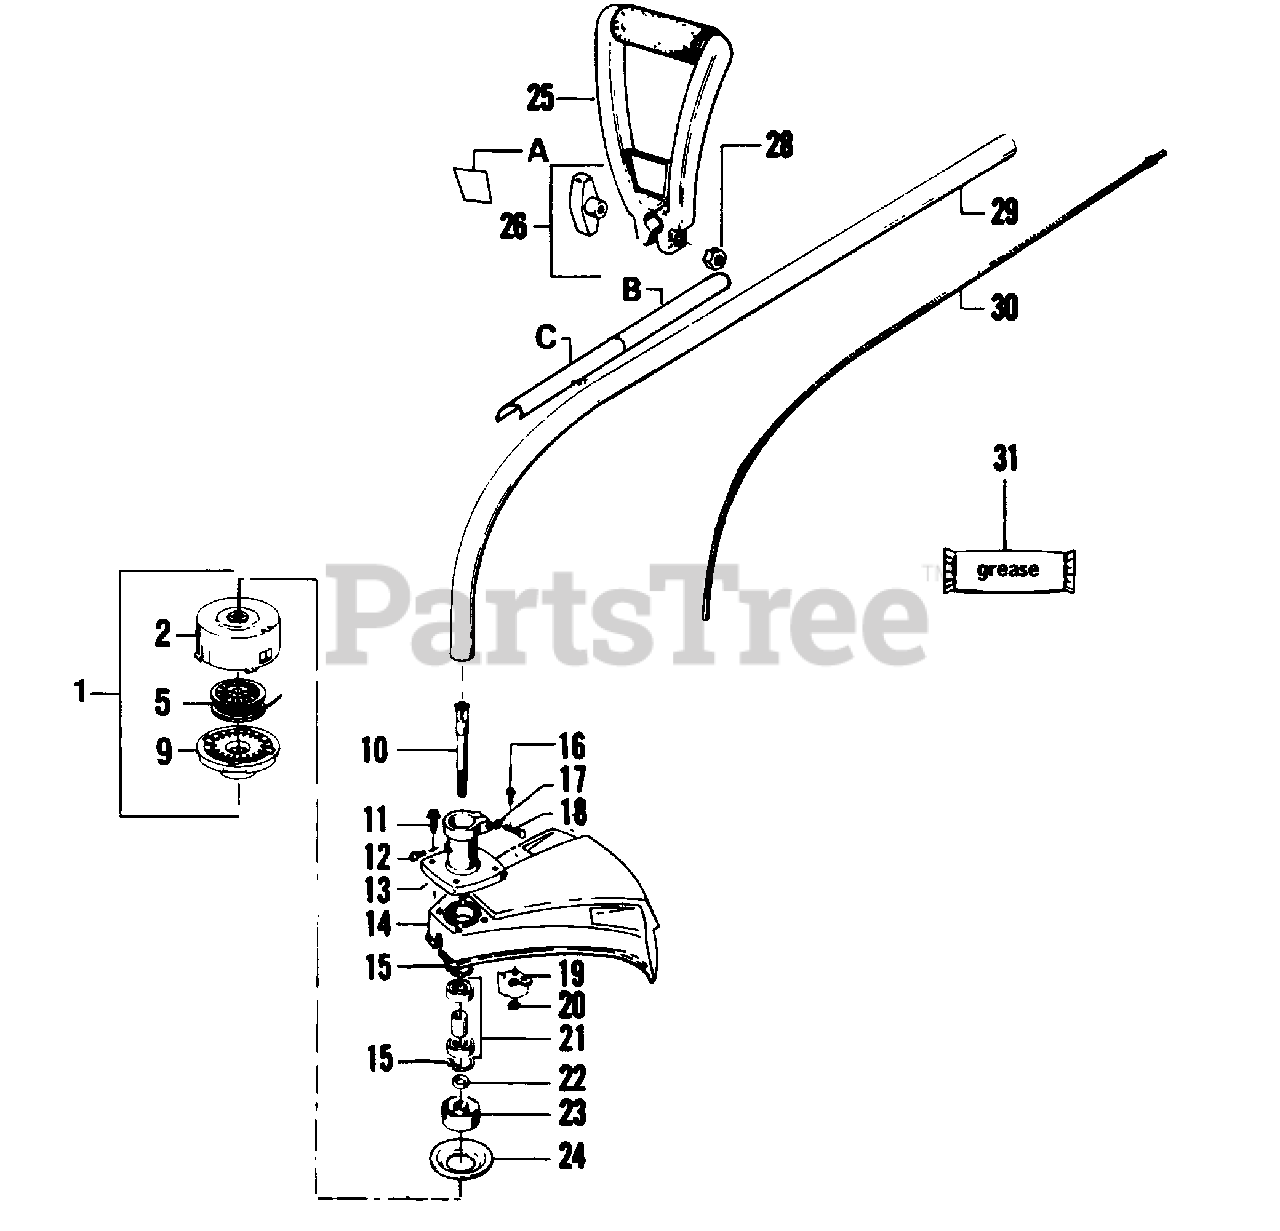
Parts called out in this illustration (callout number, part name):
1	Cutting Head Assembly (Inc. 2, 5 & 9)
2	Hub w/Line Saver
5	Spool w/Line
10	Shaft-Arbor
11	Screw-Shield to Bearing housing #1/4-10x1-1/8"
12	Screw-Self-Tapping-#10-16x1/4"
13	Bearing Housing Ass'y. (Inc. 10, 15, 17, 18, 21, 22, & 23)
14	Shield (Inc. #16, 19 & 20)
15	Retainer-Bearing
16	Screw-Line Limiter-#10-24x5/8"
17	Washer-#1/4-Int. Tooth Lock
18	Screw-Pinch Clamp-#1/4-20x1"
19	Line Limiter
20	Nut-Locking-#10-24
21	Bearings and Spacer Kit
22	Washer-Dust Cup
23	Dust Cup
25	Assist Handle
26	"T" Handle Kit
27	Washer-#1/4 Flat
29	Drive Shaft Housing
30	Flexible Drive Shaft
31	Flex Shaft Lube
A	Decal-"D" Handle
B	Decal-Safety Label (Upper)
C	Decal-Safety Label (Lower)
